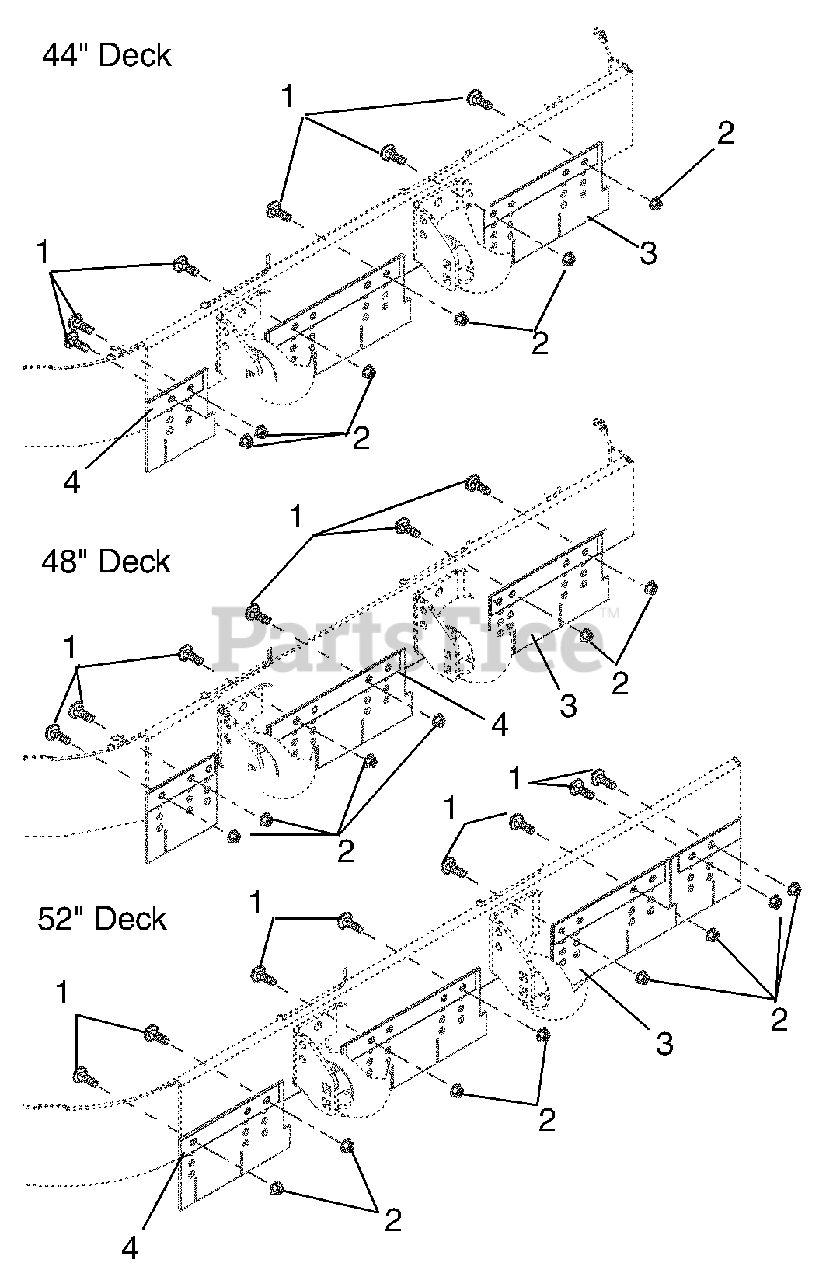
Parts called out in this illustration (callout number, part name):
1	Round Head Square Neck Bolt, 3/8"-16 x 1" Grade 5
2	Top-Locking Flange Nut, 3/8"-16
3	Rubber Striper Skirt
4	Striper Bar
